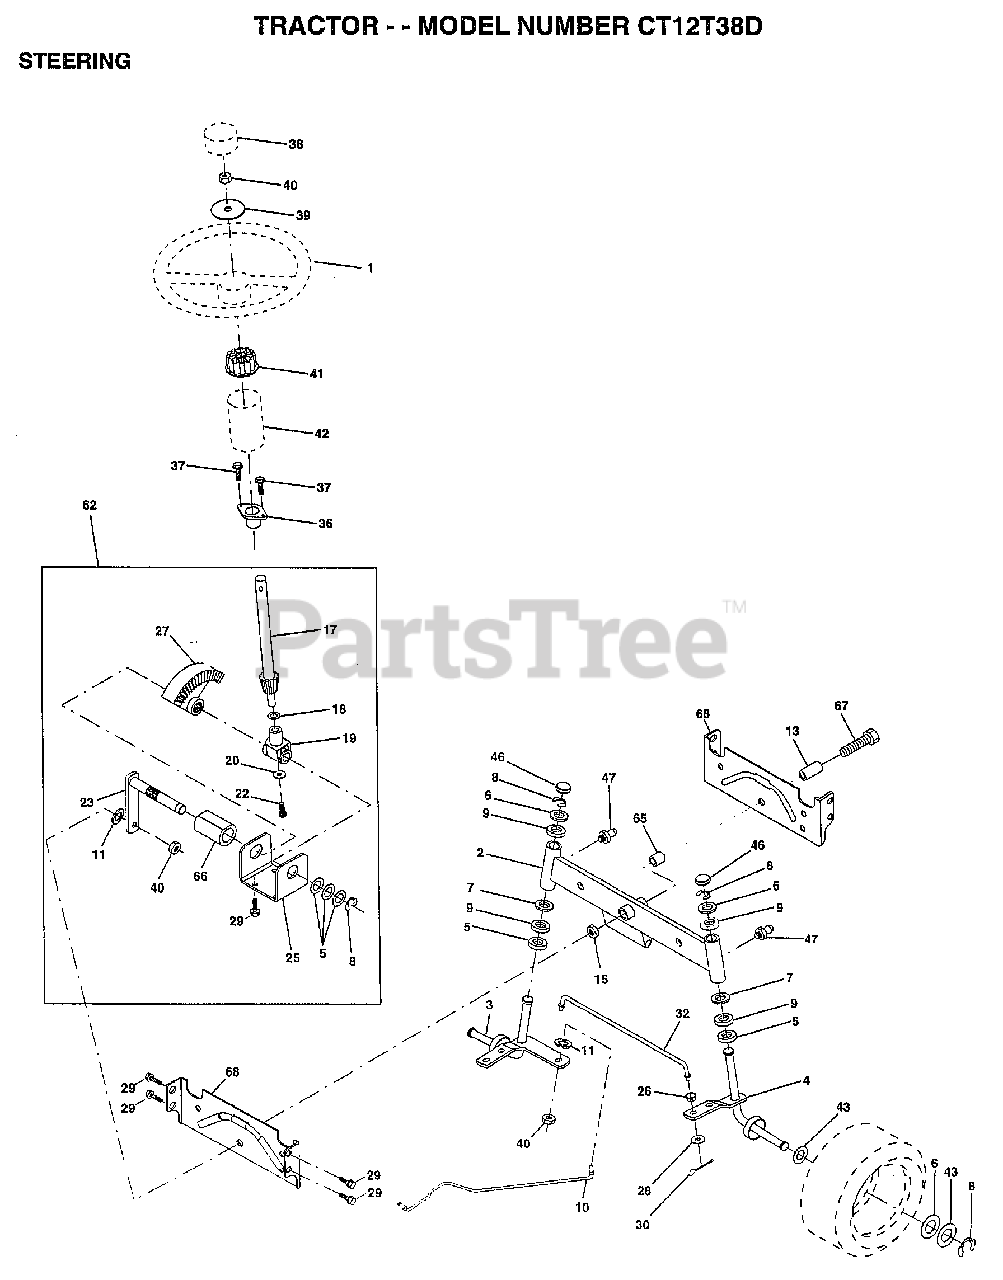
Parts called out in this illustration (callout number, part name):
2	AXLE ASM
3	SPINDLE.ASM.LH
4	"SPINDLE ASM,RH"
5	WASHER .T
6	WASHER
7	WASHER
8	RING
9	COL. SRTG. BEAR.
10	DRAGLINK-STAMPED
11	LOCKWASHER
13	BEARING AXLE
15	"NUT-LOC,FLANGE LT"
17	SHAFT ASSM STEERN
18	THRUST WASHER
19	SUPPORT.SHAFT
22	SCREW HEX SOC1/4-
25	BRKT-STEERING
26	BUSHING.DRAGLINK
27	GEAR SECTOR
28	WASHER
29	SCREW
30	COTTER PIN
32	TIE ROD
36	BUSHING.STEERING
37	"SCREW-TT,10-32 FL"
38	ST WHL INSERT CAP
39	WASHER T
40	GRIPCO NUT
41	ADAPTER-WHEEL LT
42	"TUBE, STR SHAFT"
46	CAP
47	ZERK M
62	STEERING ASM KIT
65	SPACER AXLE
66	"BEARING-ARM,PITMA"
67	BOLT
68	BRACE AXLE
